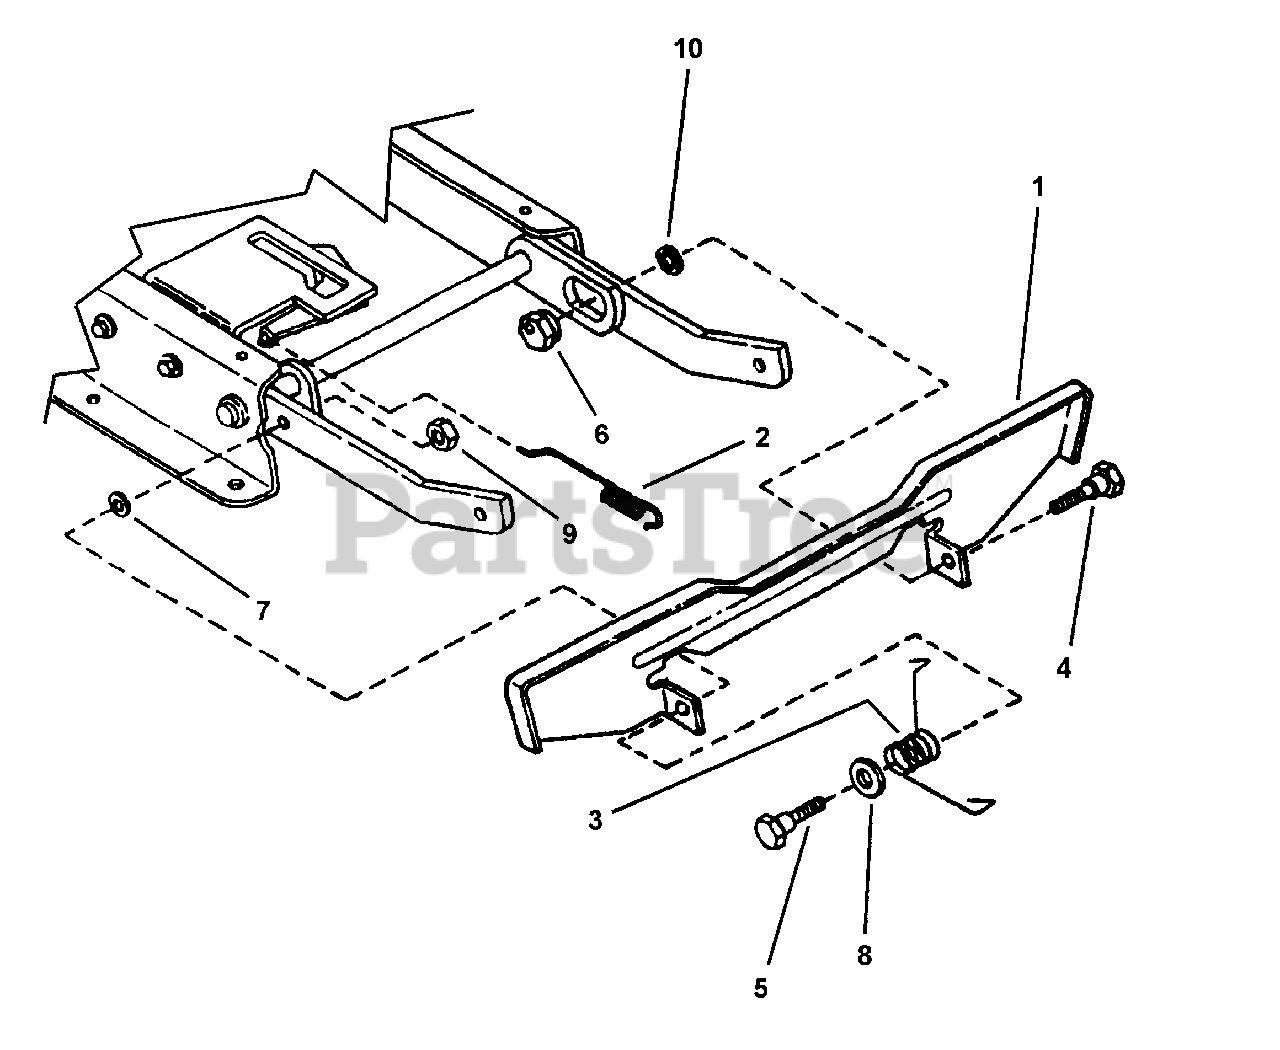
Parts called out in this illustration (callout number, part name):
1	PEDAL, Blade Stop Control
2	SPRING, Latching
3	SPRING, Pedal
4	BOLT, 3/8-24 x 3/4" Shoulder
5	BOLT, 3/8-24 x 9/16" Shoulder
6	ECCENTRIC, Leveling
7	WASHER, 3/8" Flat
8	WASHER, 1/2" Flat
9	NUT, 3/8-24 Hex Center Lock
10	WASHER, 3/8" Internal Tooth Lock
